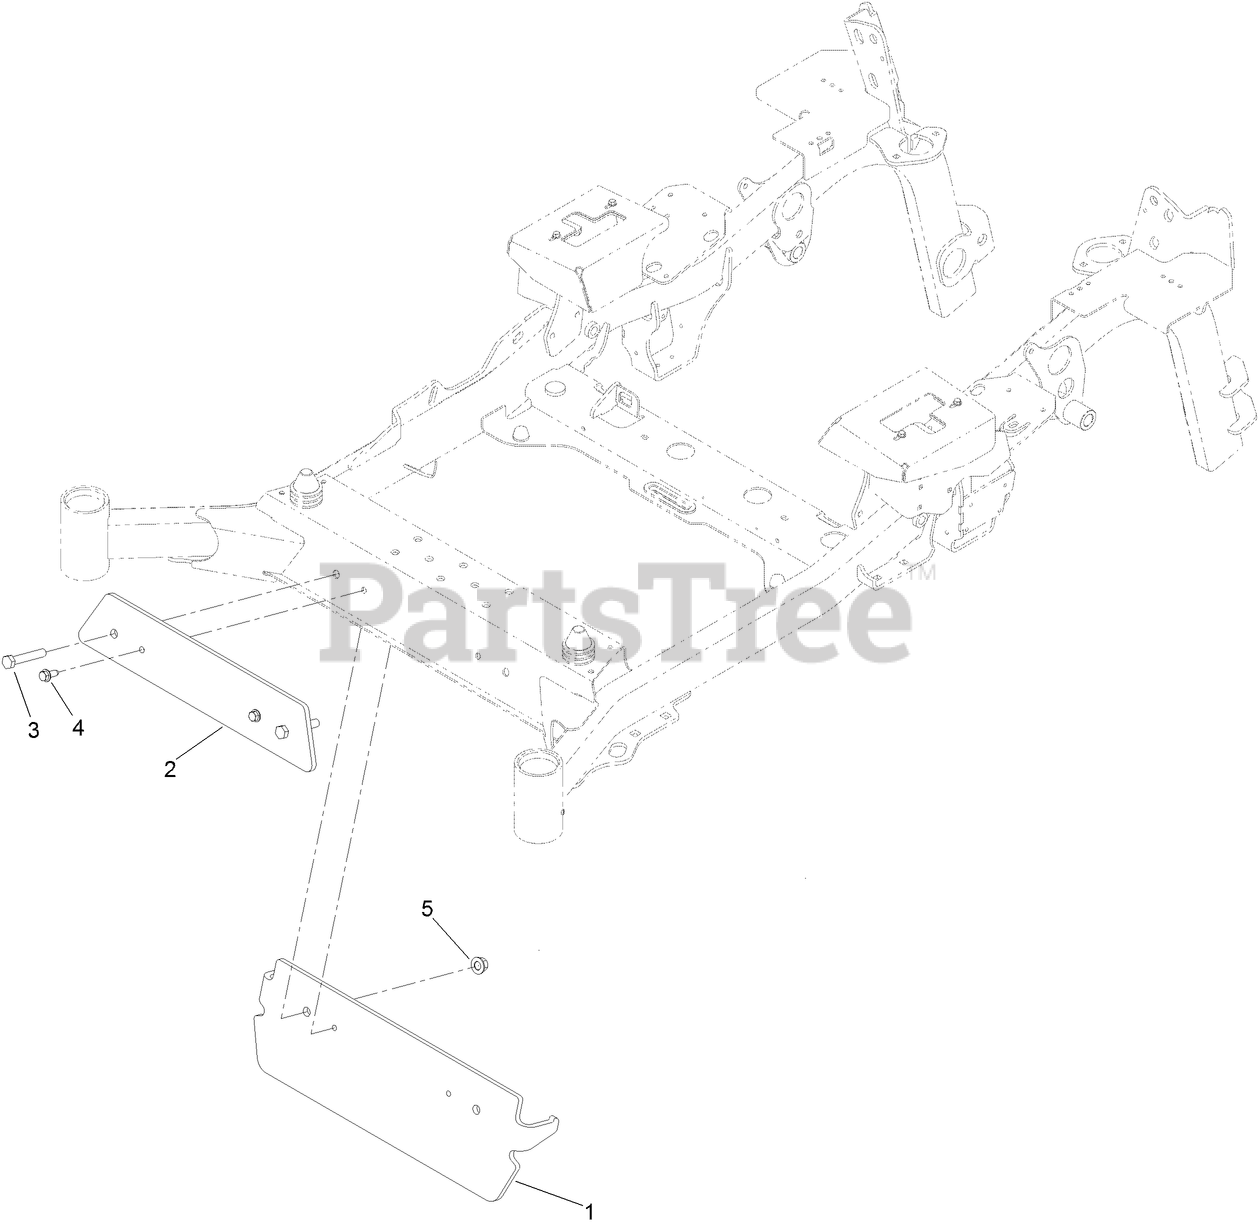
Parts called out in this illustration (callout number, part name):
1	BRACKET-WEIGHT
2	WEIGHT-OUTER
3	SCREW-HH, TAP
4	SCREW-FORMING, THREAD
5	NUT-LOCK
